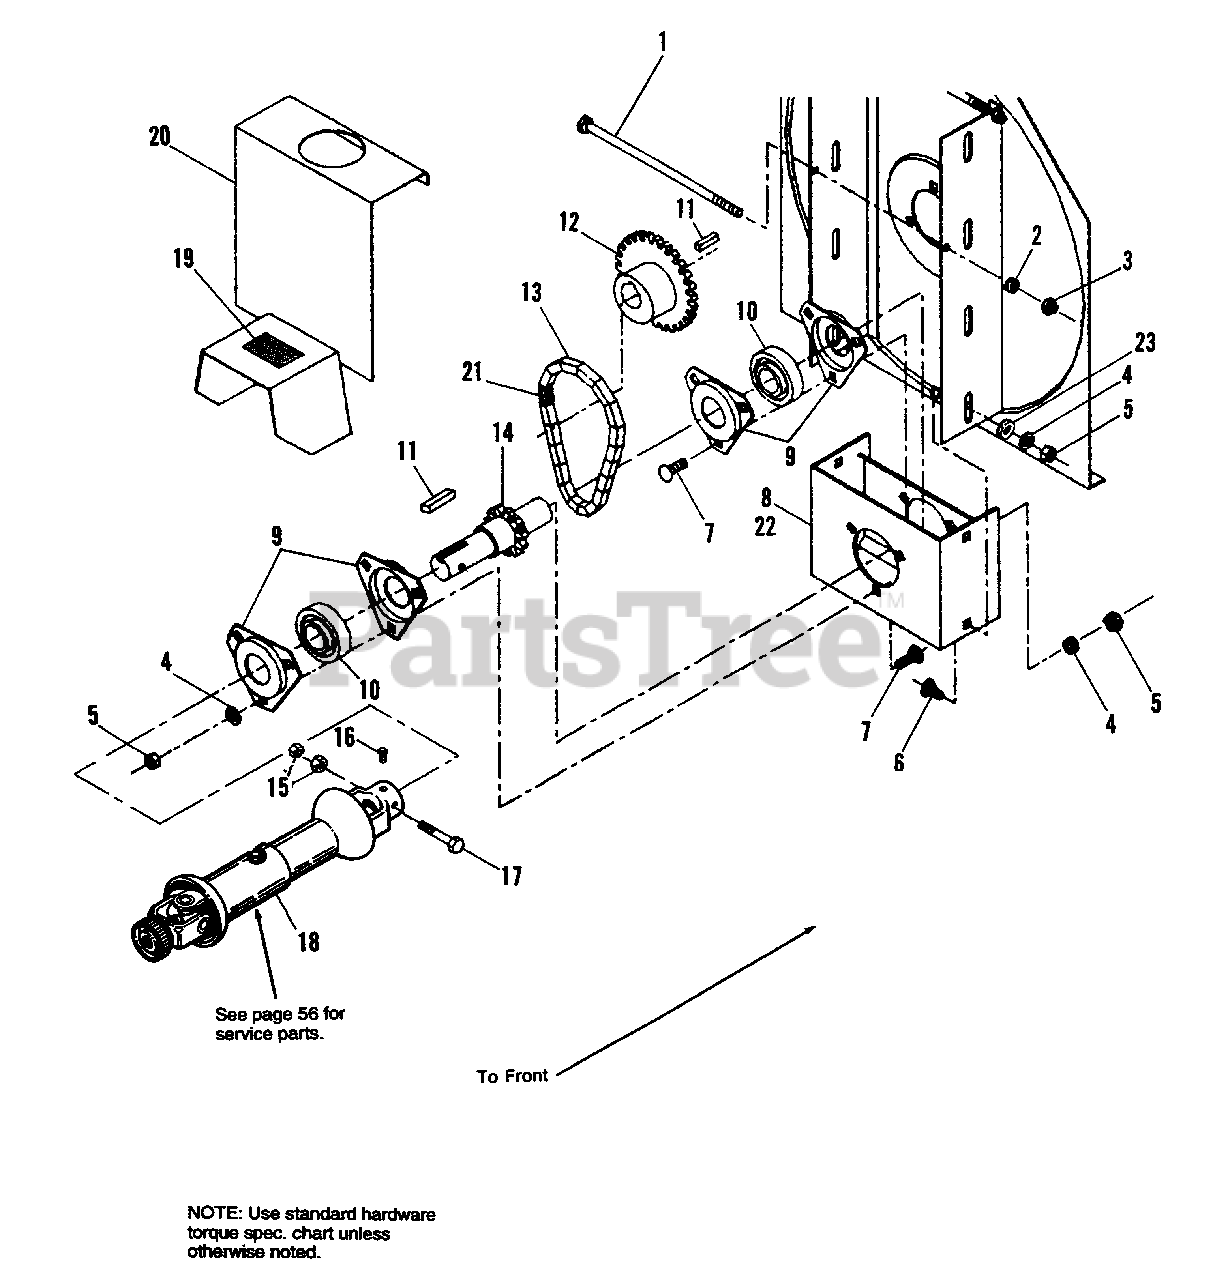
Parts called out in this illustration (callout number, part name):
1	CAPSCREW, Hex Hd., 1/4-20 x 7-1/2
2	LOCKWASHER, 1/4
3	NUT, Hex, 1/4-20
4	LOCKWASHER, 5/16
5	NUT, Hex, 5/16-18
6	BOLT, Carriage, 5/16-18 x 3/4
7	BOLT, Carriage, 5/16-18 x 5/8
8	BOX ASSY., Reduction
9	BEARING, Flange
10	BEARING, 1" I.D. w/Locking Screw
11	KEY, Parallel, Plain, 1/4 x 1/4 x 1-1/4
14	SHAFT, Assy., Drive, w/Sprocket
15	NUT, Hex Lock, 1/4-20
16	SETSCREW, Sq. Hd., 5/16-18 x 5/8
17	CAPSCREW, Hex Hd., 1/4-20 x 2-1/2
18	DRIVE SHAFT
19	DECAL, Danger
20	SHIELD, P.T.O.
21	MASTER LINK, Chain #40
22	BOX, Reduction
23	WASHER
